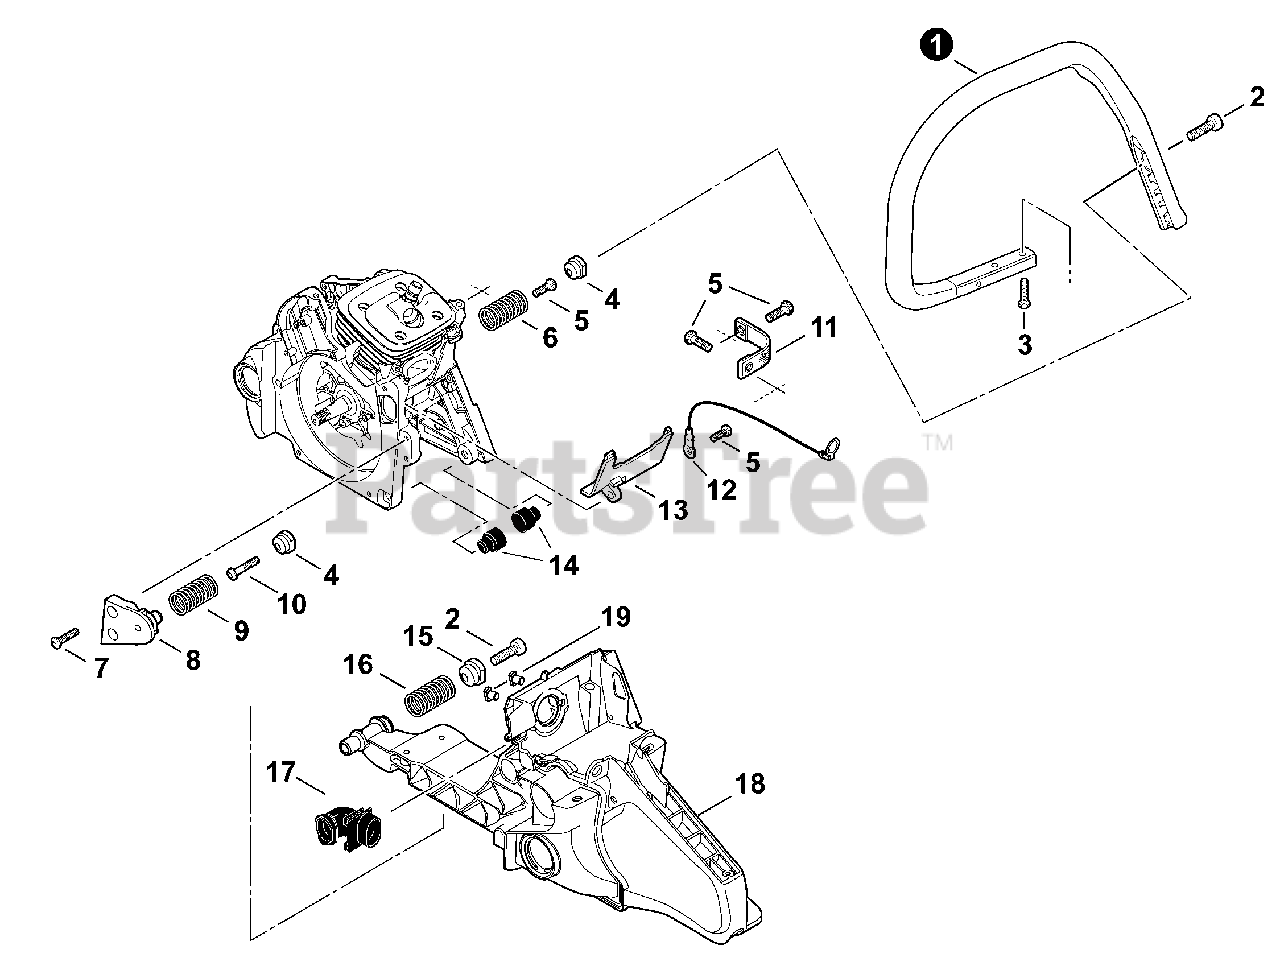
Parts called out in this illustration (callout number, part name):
1	HANDLE, FRONT
2	BOLT, TORX 6×20
3	BOLT, TORX 5×20
4	HOLDER, SPRING 14.4
5	BOLT, TORX 5×16
6	SPRING, COMPRESSION 17×38.4×2.6
7	BOLT, TORX 5×20
8	HOLDER, SPRING
9	SPRING, COMPRESSION 17×36.7×2.6
10	BOLT, TORX 5×25
11	STRAP, SAFETY
12	LEAD - GROUND L= 170
13	GUIDE, AIR
14	CUSHION
15	HOLDER, SPRING 17
16	SPRING, COMPRESSION 20×40×3.3
17	PIPE, AIR INTAKE
18	HANDLE, REAR
